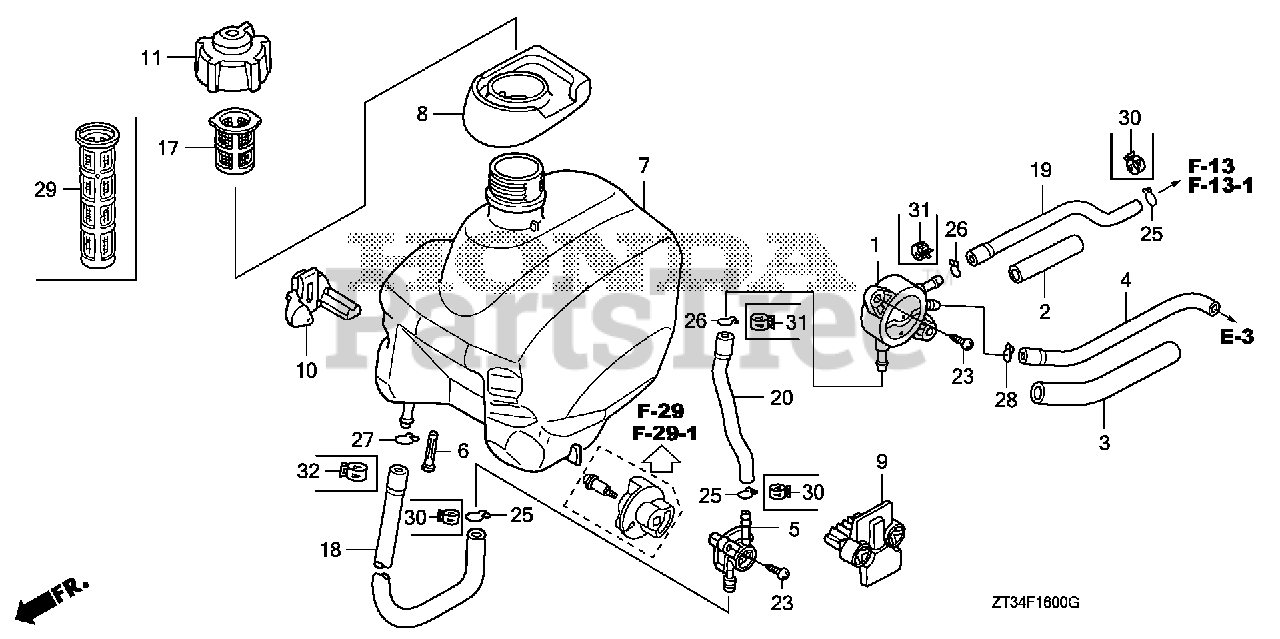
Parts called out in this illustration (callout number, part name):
1	PUMP ASSY., FUEL (MSDS)
2	RUBBER A, SUPPORTER
3	RUBBER B, SUPPORTER
4	TUBE, DIAPHRAGM
5	PETCOCK ASSY.
6	FILTER, FUEL
7	TANK, FUEL
8	SEAL, FUEL FILLER NECK
9	RUBBER R, TANK MOUNTING
10	RUBBER L, TANK MOUNTING
11	CAP ASSY., FUEL TANK
18	TUBE, FUEL TANK
19	TUBE A, FUEL
20	TUBE B, FUEL
23	SCREW, TAPPING (5X20) (PO)
25	CLIP, TUBE (B8)
26	CLIP, TUBE (C9)
27	CLIP, TUBE (C11)
29	FILTER, FUEL
